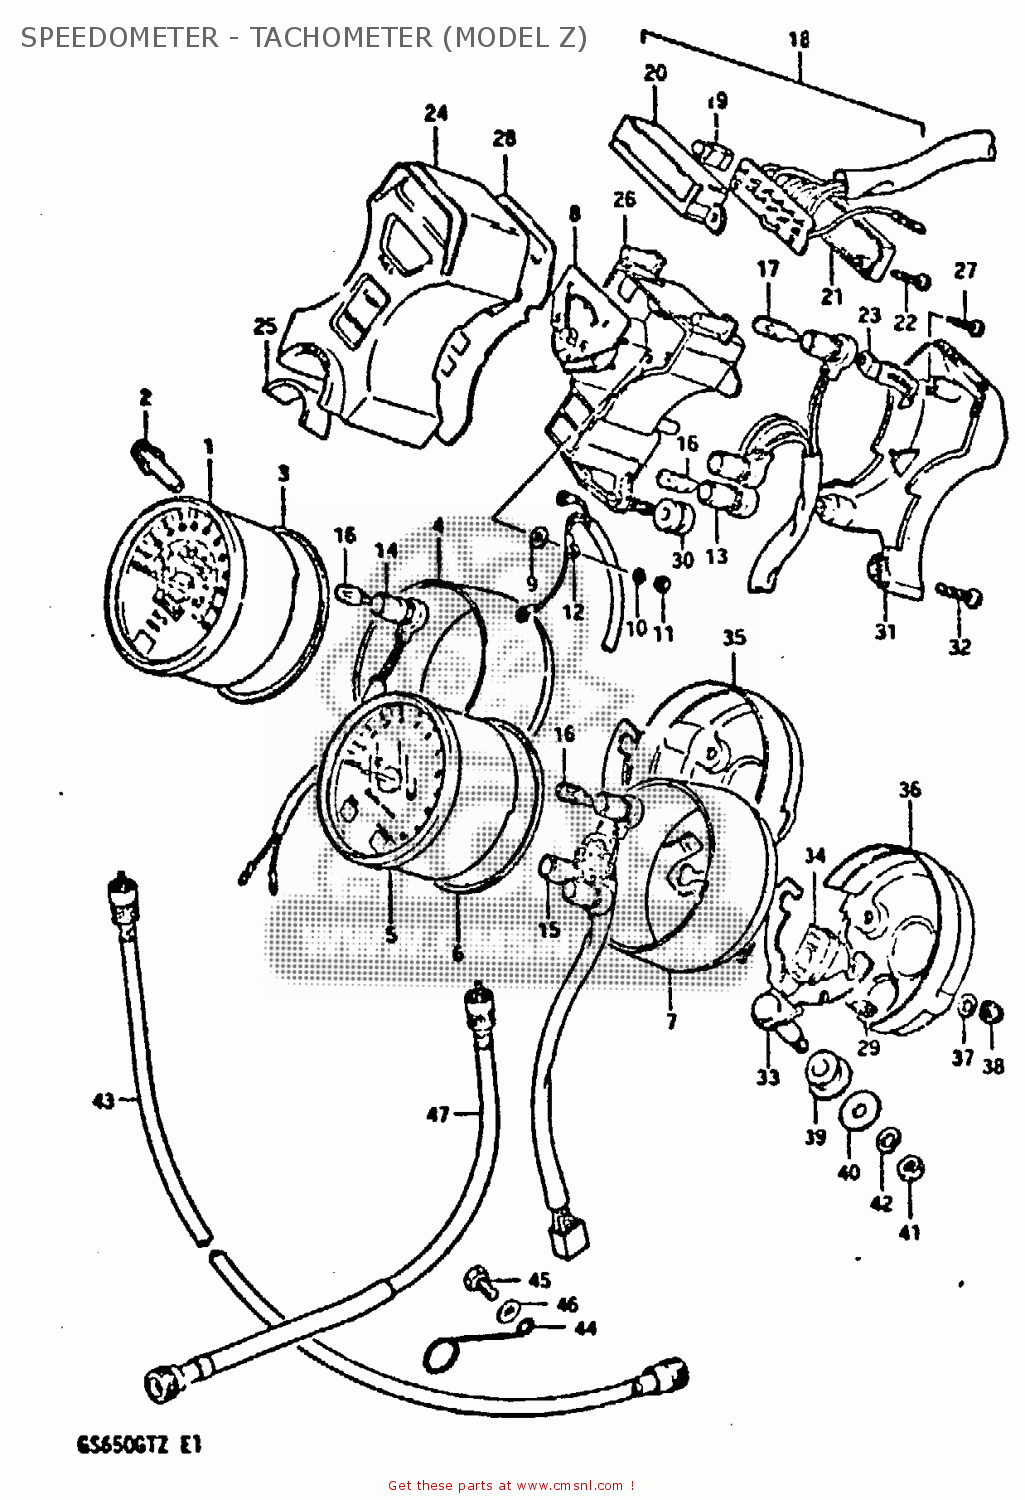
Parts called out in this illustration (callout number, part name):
1	SPEEDOMETER (MILE/KILO)
2	KNOB
3	CUSHION,SPEEDOMETER
4	COVER,SPEEDOMETER
5	TACHOMETER
6	CUSHION,SPEEDOMETER
7	COVER,TACHOMETER
8	METER,FUEL
9	WASHER,FUEL METER
10	LOCK WASHER
11	NUT 3MM
12	LEAD WIRE, FUELMETER
13	SOCKET
14	SOCKET,METER
15	SOCKET,TACHOMETER
16	BULB(12V3.4W,T10)
17	BULB(12V1.7W,T10,WB121)
18	INDICATOR ASSEMBLY,GEAR POSITION
19	BULB(14V1.12W)
20	CASE,GEAR INDICATOR
21	COVER,LWR
22	SCREW,GEAR INDICATOR
23	CLAMP,CORD
24	CASE,PILOT BOX
25	SEAL,IGNITION SWITCH
26	CASE,PILOT BOX,INNER
27	SCREW,INDICATOR
28	PLATE,PILOT BOX
29	CUSHION
30	CUSHION,PILOT BOX
31	COVER,PILOT BOX,UNDER
32	SCREW
33	BRACKET,COMBINATION METER
34	CUSHION,METER
35	COVER,METER,UNDER
36	PLATE,TACHOMETER UNDER
37	WASHER
38	NUT
39	CUSHION,METER BRACKET
40	WASHER (8.5X29X1.6)
41	NUT
42	LOCK WASHER
43	CABLE ASSEMBLY,SPEEDOMETER
44	CLAMP,SPEEDOMETER CABLE
45	BOLT, UPPER
46	WASHER
47	CABLE ASSEMBLY,TACHOMETER
